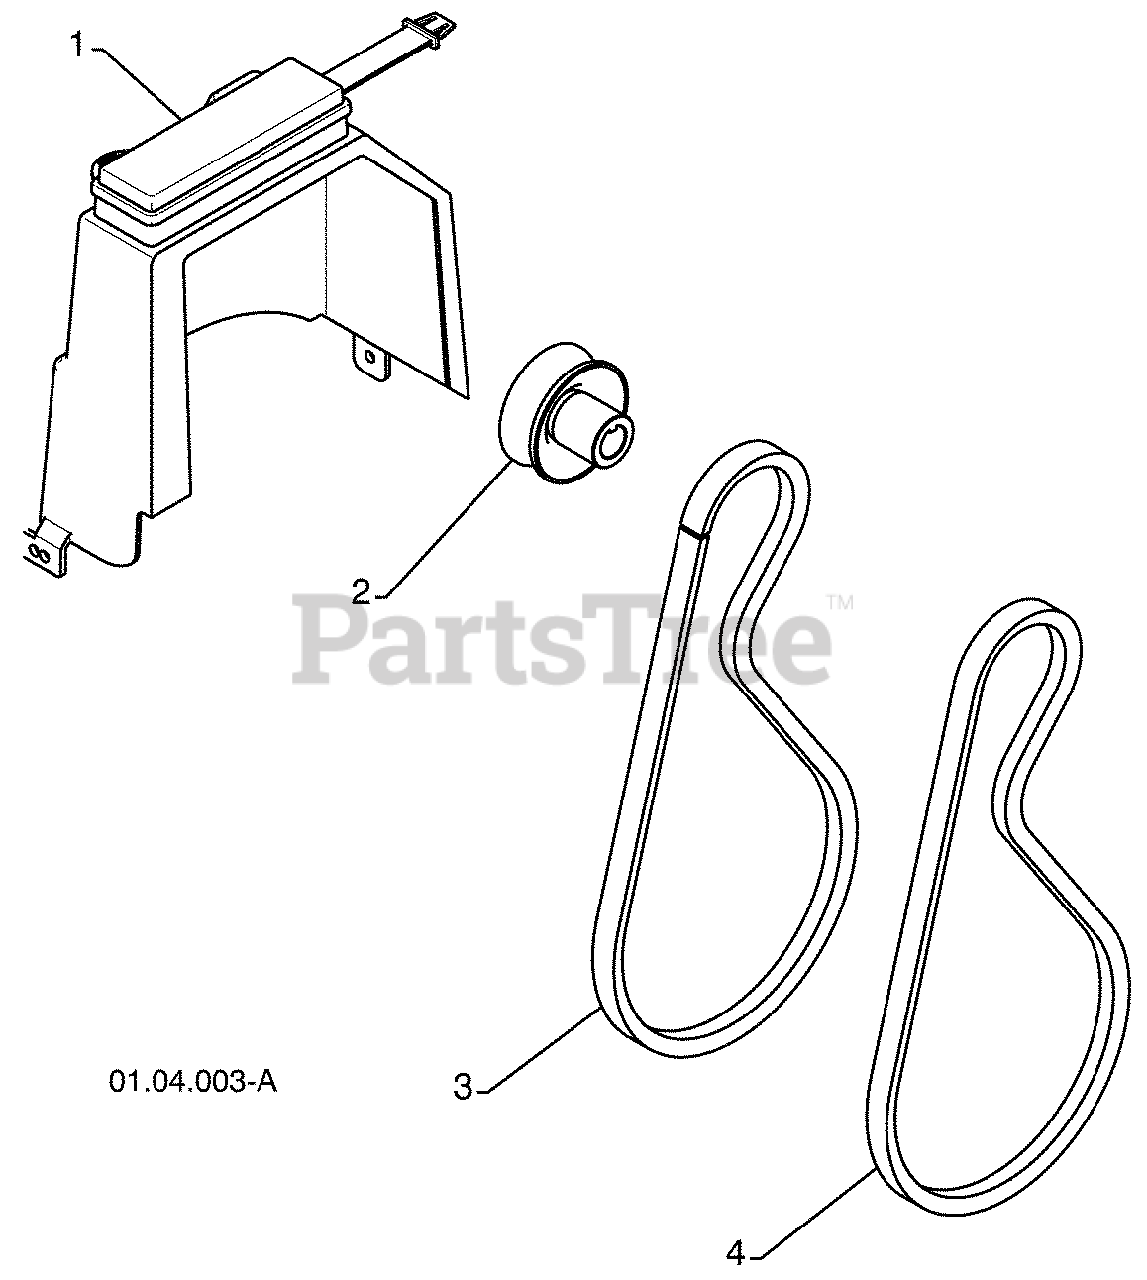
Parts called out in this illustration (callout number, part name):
1	COVER ASSEMBLY
2	PULLEY
3	TRACTION BELT
4	IMPELLER BELT
